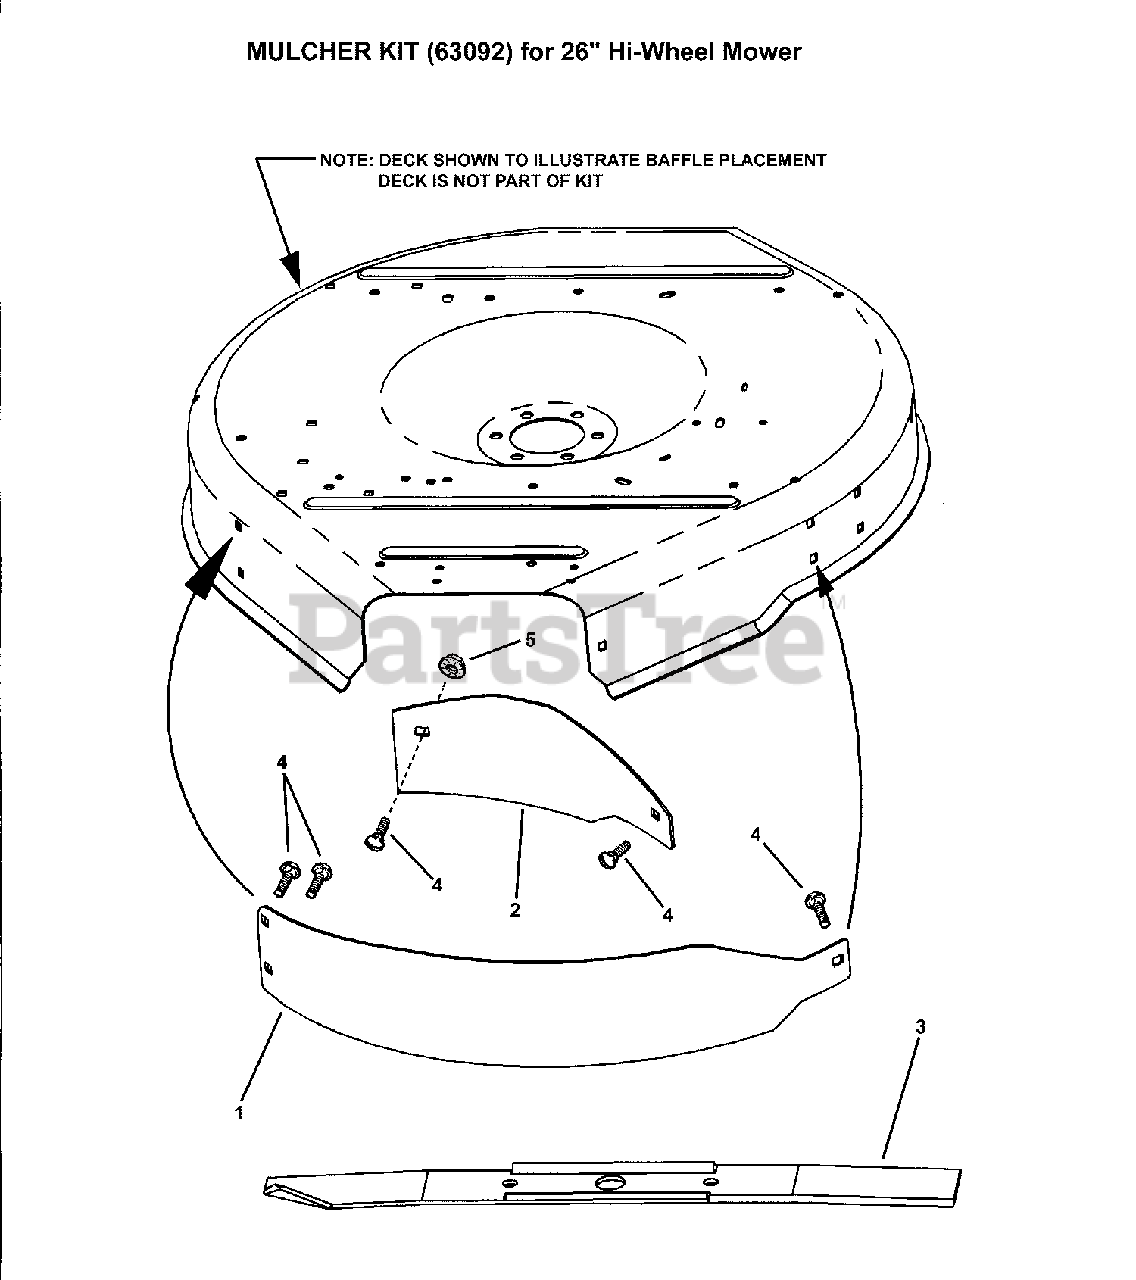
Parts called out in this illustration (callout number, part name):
1	BAFFLE, Right
2	BAFFLE, Left
3	BLADE, 26" Mulcher
4	BOLT, 5/16-18 x 3/4" Short Neck Carriage, GR5
5	NUT, 5/16-18 Hex Flange Lock
